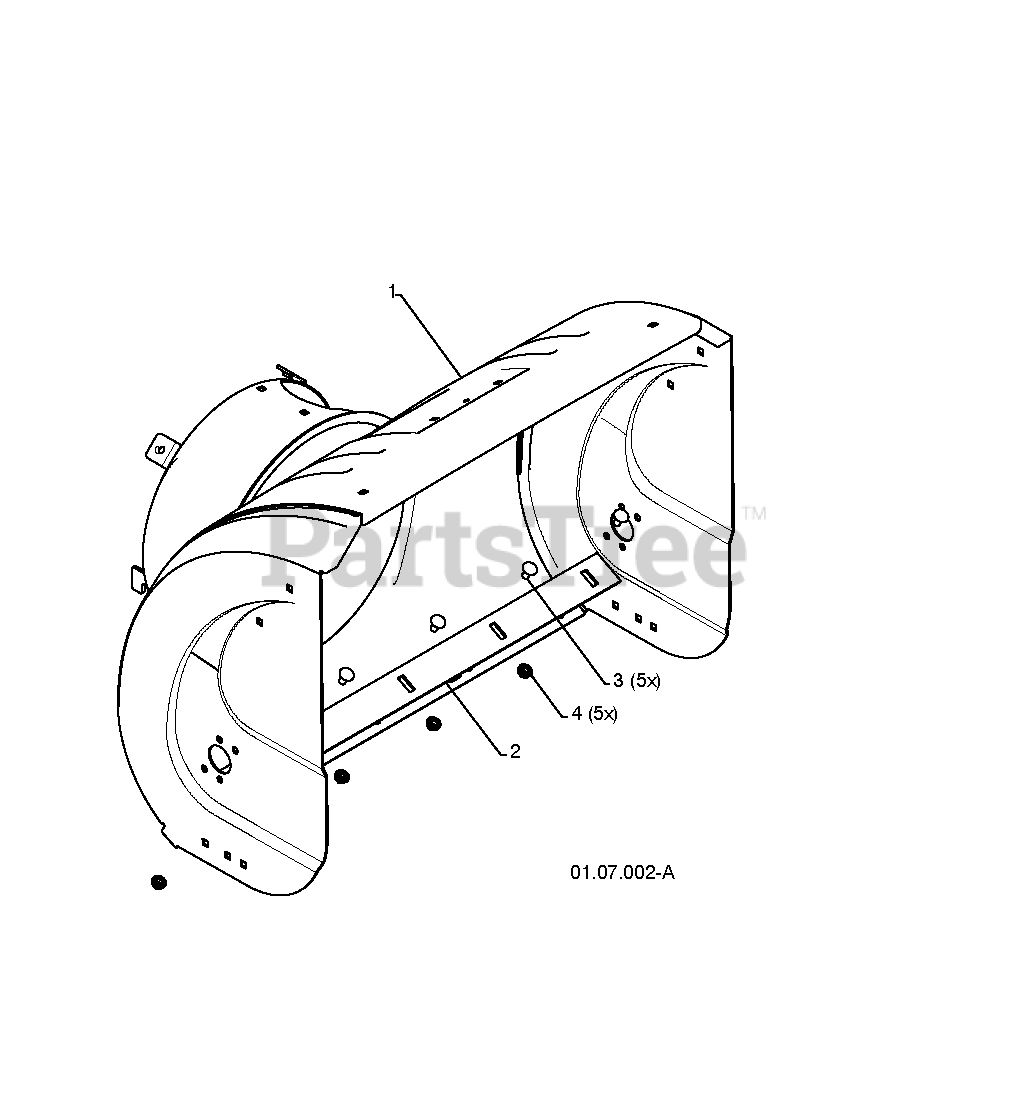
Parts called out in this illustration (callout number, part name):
1	HOUSING.AUG.WELDMENT.27.BLACK
2	BAR.SCRAPER.27.PNT.BLACK
3	BOLT
4	NUT.FLANGE.5/16
